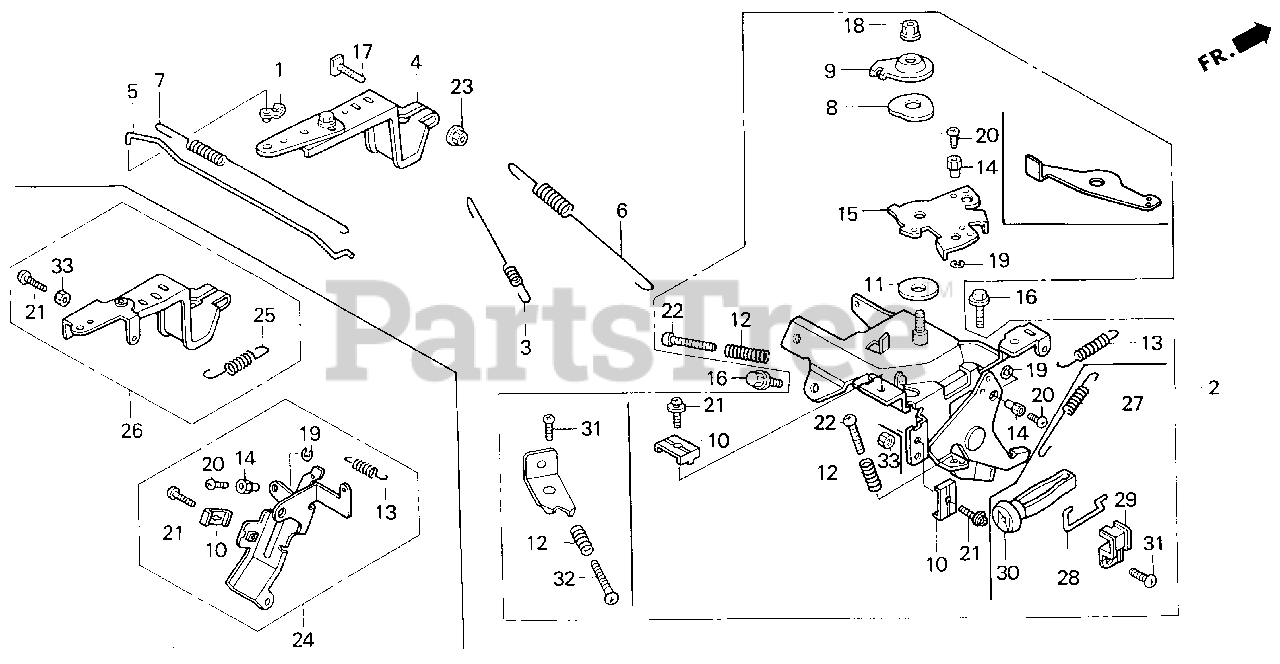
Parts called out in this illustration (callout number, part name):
1	JOINT, ROD
2	CONTROL ASSY. (REMOTE)
3	SPRING, STARTER
4	ARM, GOVERNOR
5	ROD, GOVERNOR
6	SPRING, GOVERNOR
7	SPRING, THROTTLE RETURN
8	SPRING, LEVER
9	WASHER, CONTROL LEVER
10	HOLDER, CABLE
11	SPACER, CONTROL LEVER
12	SPRING, CONTROL ADJUSTING
13	SPRING, CABLE RETURN
14	HOLDER, WIRE
15	LEVER, WIRE
16	BOLT, FLANGE (6X12) (CT200)
17	BOLT, GOVERNOR ARM
18	NUT, SELF-LOCK (6MM)
19	CIRCLIP (5MM)
20	SCREW, PAN (4X6)
21	SCREW, PAN (5X16)
22	SCREW, PAN (5X25)
23	NUT, FLANGE (6MM)
